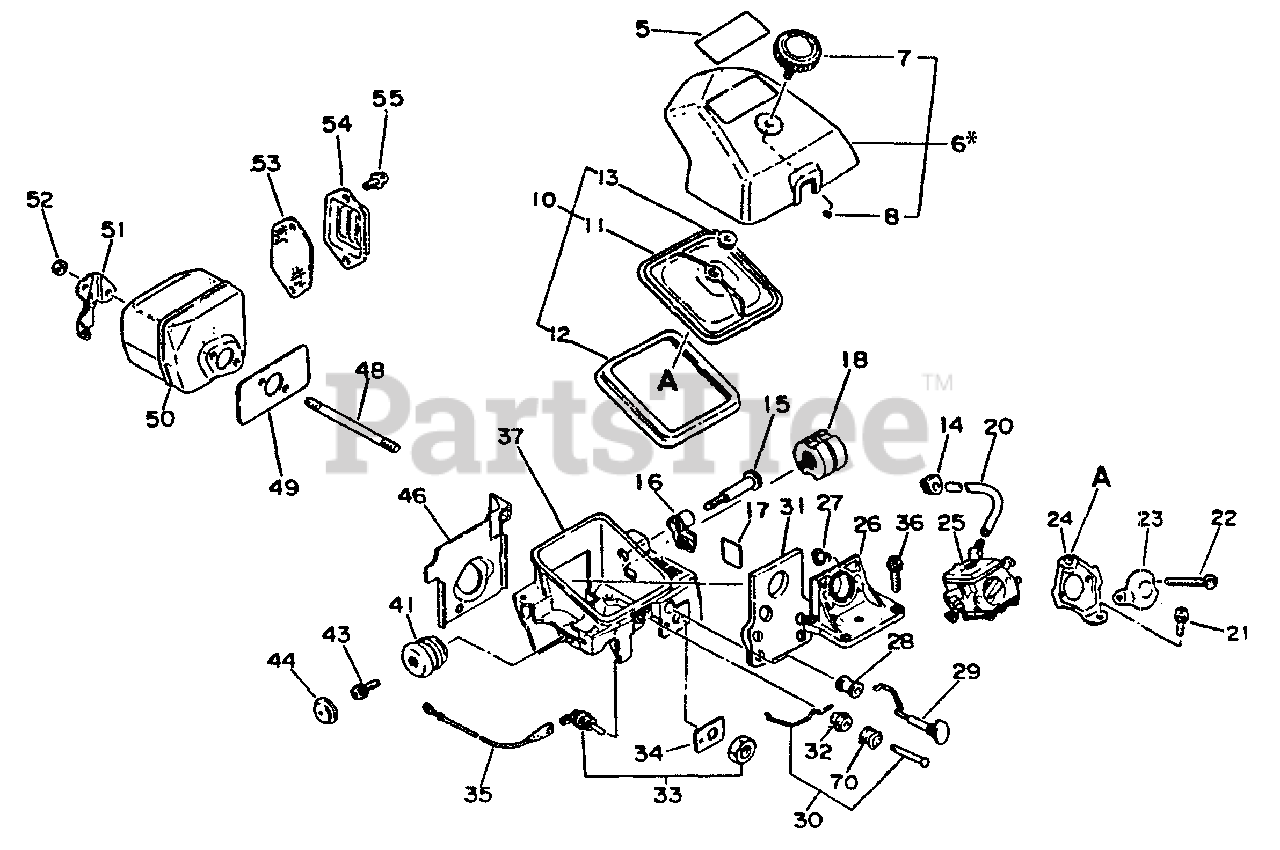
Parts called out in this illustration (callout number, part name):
5	LABEL
6	AIR FILTER COVER ASSY
7	THUMBSCREW
8	O-RING - 3
10	AIR FILTER COVER ASSY
11	FILTER, AIR
12	SEAL
14	BUSHING
15	SCREW, IDLE ADJUST
20	PIPE - IMPULSE
21	SCREW - 5X14
22	SCREW - 5X55
23	PLATE, PREVENT
24	BRACKET, AIR CLEANER
25	CARBURETOR
26	INSULATOR, INTAKE
27	NUT
29	ROD, CHOKE
30	ROD, THROTTLE
31	SEAL
32	GUIDE, THROTTLE ROD
33	IGNITION SWITCH ASSY
34	LABEL - STOP
35	LEAD - GROUND
36	SCREW - 5X25
37	CASE, CARBURETOR
41	CUSHION
43	SCREW - 5X10
44	CAP, CUSHION
46	INSULATOR
48	STUD
49	GASKET, EXHAUST
50	MUFFLER
52	LOCKNUT - 5
53	SCREEN, SPARK ARRESTOR
54	LID, MUFFLER
55	SCREW - 4X8
